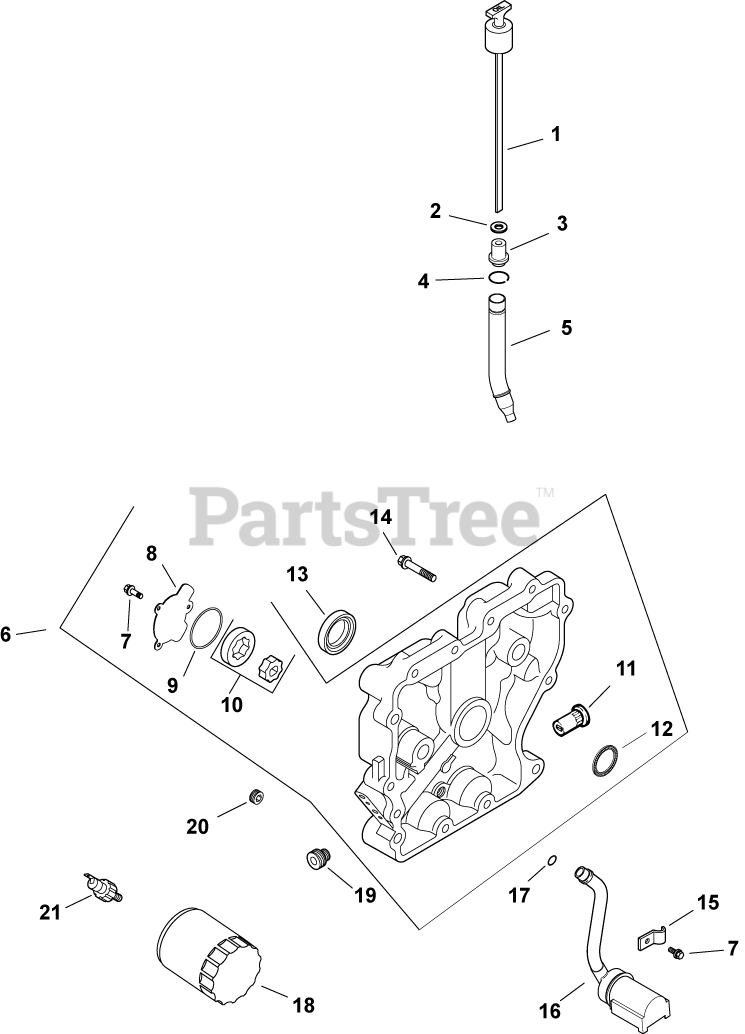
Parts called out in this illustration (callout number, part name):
1	DIPSTICK - DISCONTINUED
3	SEAL USE 25 032 13-S
5	TUBE, OIL FILL - DISCONTINUED
6	PLATE, CLOSURE & BEARING
7	SCREW,FLG THD FRM M5X0.8X16-(#25086398S)
8	COVER, OIL PUMP
9	O-RING (1.78" DIA)
10	PUMP ASSEMBLY, OIL
11	VALVE, OIL PRESSURE RELIEF
12	BEARING, CRANKSHAFT
13	SEAL, OIL
14	SCREW, FLG M8X1.25X45
16	KIT, OIL PICK-UP
17	O-RING (.5" DIA)
18	OIL FILTER
19	NIPPLE, OIL FILTER
20	PLUG, CTSK PIPE 1/8"
21	SWITCH, PRESSURE
